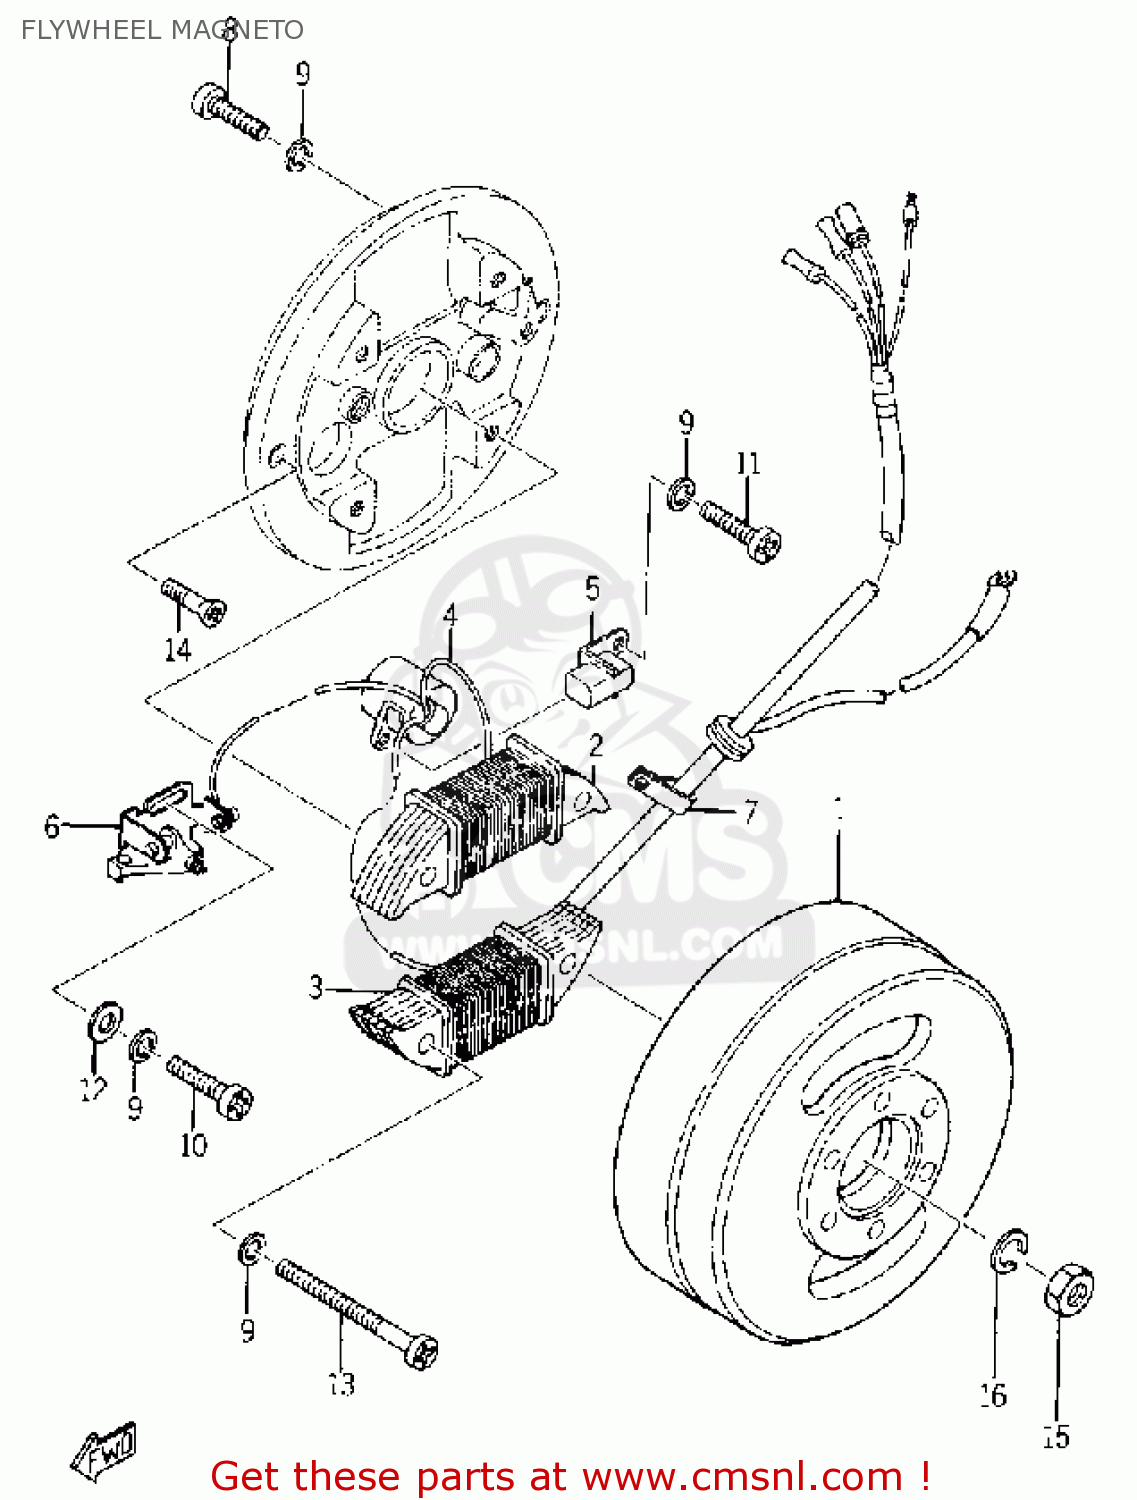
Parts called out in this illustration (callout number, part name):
1	FLYWHEEL MAGNETO ASSY
2	COIL, SOURCE
3	COIL, LIGHTING
4	CONDENSER
5	LUBRICATOR
6	CONTACT BREAKER ASSY
7	CLAMP, LEAD
8	SCREW, PAN HEAD
9	WASHER, SPRING
10	SCREW, PAN HEAD
11	SCREW, PAN HEAD
12	YBS66-4 WASHER, PLAIN
13	SCREW, PAN HEAD
14	SCREW, FLAT HEAD
15	NUT SELFLOCKING 214214940000
16	YBS67-10 WASHER, SPRING
